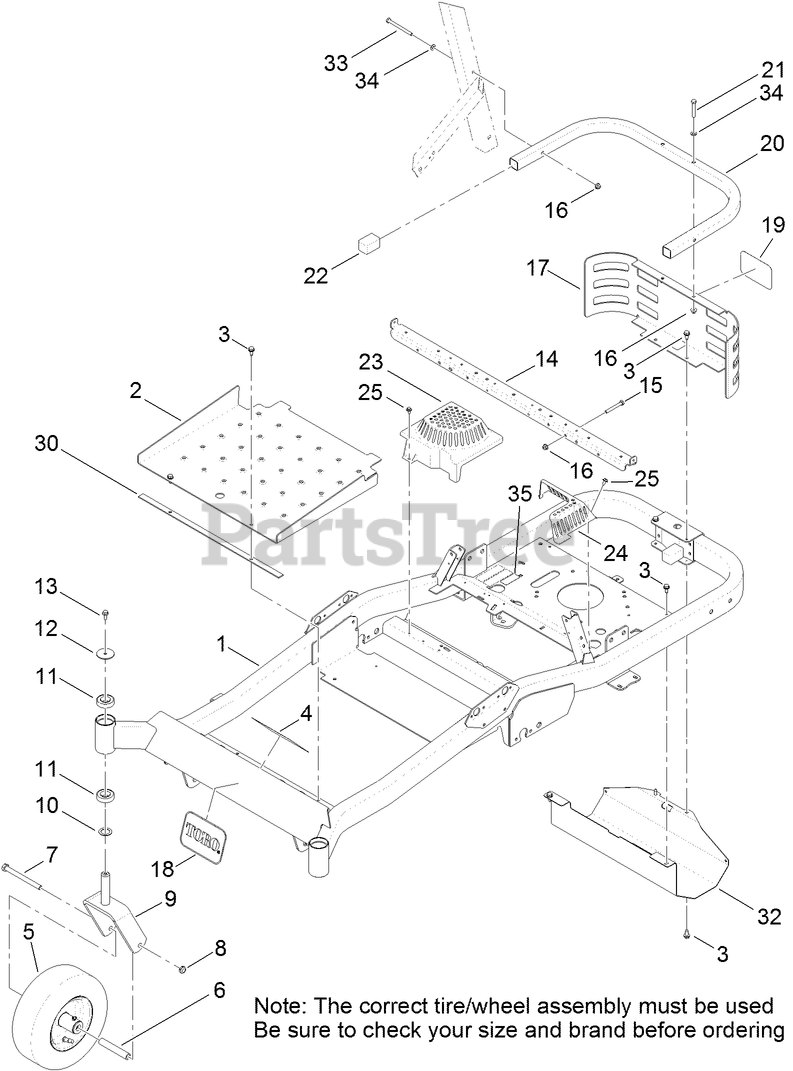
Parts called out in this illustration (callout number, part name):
2	PAN-FLOOR
3	SCREW-HWHTF
4	DECAL-SAFETY
5	TIRE AND WHEEL ASM (KENDA)
5	TIRE AND WHEEL ASM (C S T)
6	BUSHING-SPANNER
7	SCREW-HH
8	NUT-HEX
9	CASTER FORK ASM
10	WASHER-THRUST
11	BEARING-BALL
12	WASHER
13	SCREW-HHF
14	SUPPORT-SEAT
15	SCREW-HH
16	NUT-HF, NI
17	GUARD-REAR
18	DECAL
20	TUBE-GUARD
21	SCREW-HH
23	COVER-FAN, RH
24	COVER-FAN, LH
25	SCREW-HHFTF
30	STRIP-VIBRATION, ANTI
33	SCREW-HH
34	WASHER-PLAIN
35	DECAL-LOCATION, SERVICE DEALER
